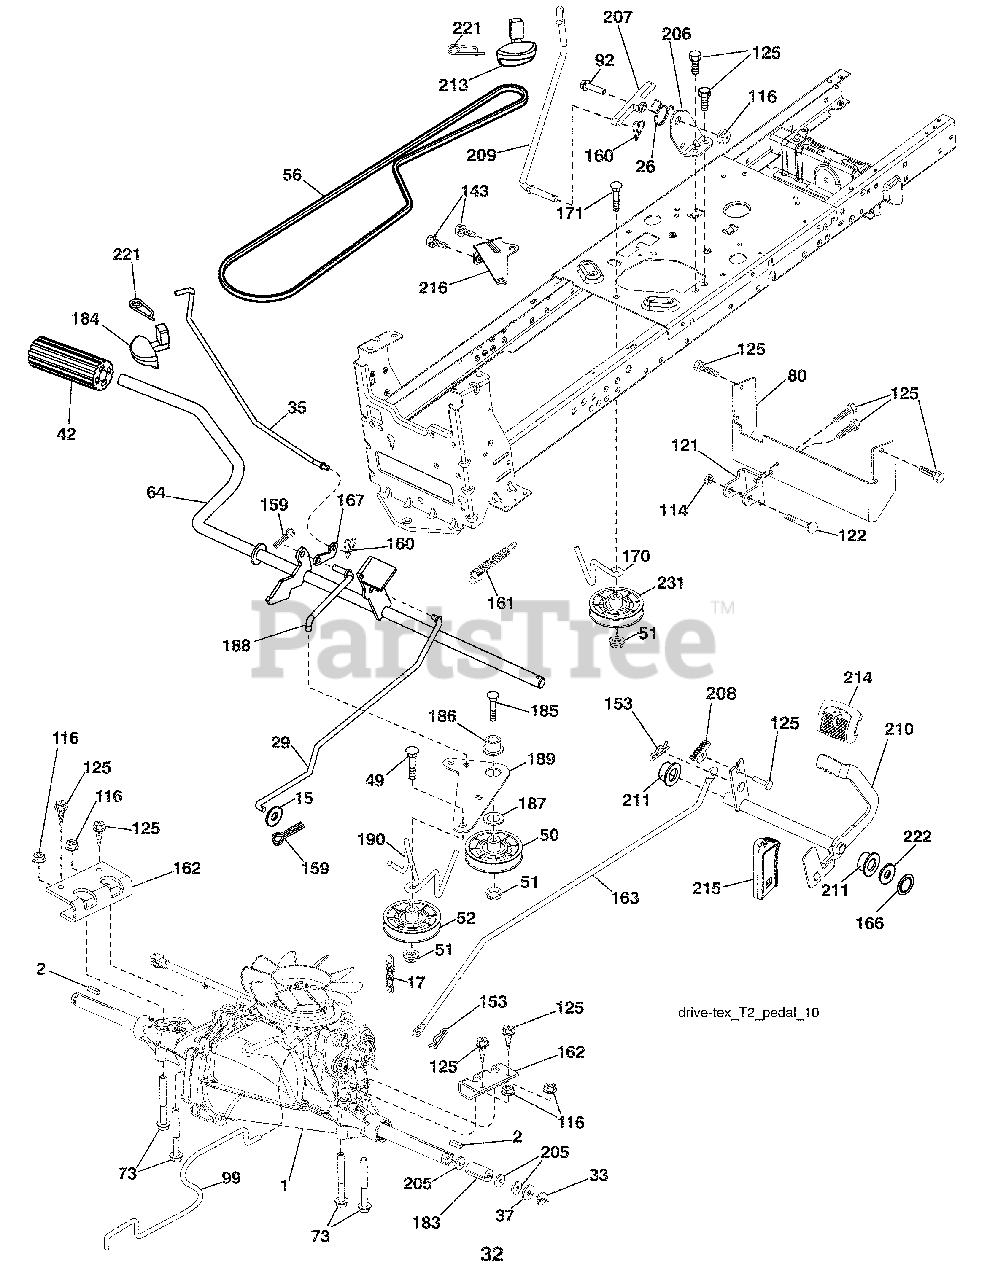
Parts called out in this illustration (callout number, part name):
2	Key Square
15	Washer 13/32 x 13/16 x 16 Ga.
17	Spring, Brake
26	Spring Return Cruise
29	Rod, Brake
35	Rod, Brake, Park
37	Washer 25/32 x 1-1/4 x 16 Ga.
42	Cover, Foot Pedal
50	Pulley Idler Flat
51	Lock Nut 3/8-16
52	Idler V-Groove 910" Offset
56	V-Belt, Drive
64	Shaft Asm. Pedal Brake Control
73	Bolt Hex 5/16-18 Gr. 5
80	Strap Torque
92	Bolt Fin Hex 5/16-18 unc x 1.25
99	Rod Spring Bypass
114	Nut Lock HX W/Ins 5/16-18
116	Nut Lock Hex Flange 5/16-18
121	Bracket Strap Torque
122	Bolt 5/16-18 x 2.50
125	Screw 5/16-18 x 3/4
143	Screw 5/16-18 x 1/2
153	Retainer Spring 1"
159	Pin Cotter 1/8 x 3/4
160	Retainer Clip
161	Spring, Return, Clutch
162	Adapter Transaxle
163	Rod Control
166	Nut Push
167	Latch Brake Parking
170	Keeper V-Idler
183	Spacer Axle
184	Handle Parking Brake
186	Spacer Retainer
187	Washer
188	Link Clutch Ground Drive
189	Bellcrank Ground Drive
190	Keeper Bellcrank Ground Drive
205	Washer 25/32 x 1-5/8 x 16 Ga.
206	Bracket Mount Latch Cruise
207	Latch Control Cruise
208	Gear Sector Control Cruise
209	Rod Control Cruise
210	Rocker Asm. Pedal Control
211	Bearing Nylon
213	Knob Control Cruise
214	Pedal Forward
215	Pedal Reverse
216	Bracket Pulley Idler
221	Retainer Spring Clip Handle
222	Washer 21/32 x 1-1/4 10 Ga.
231	Idler V-Groove 1.688" Offset
